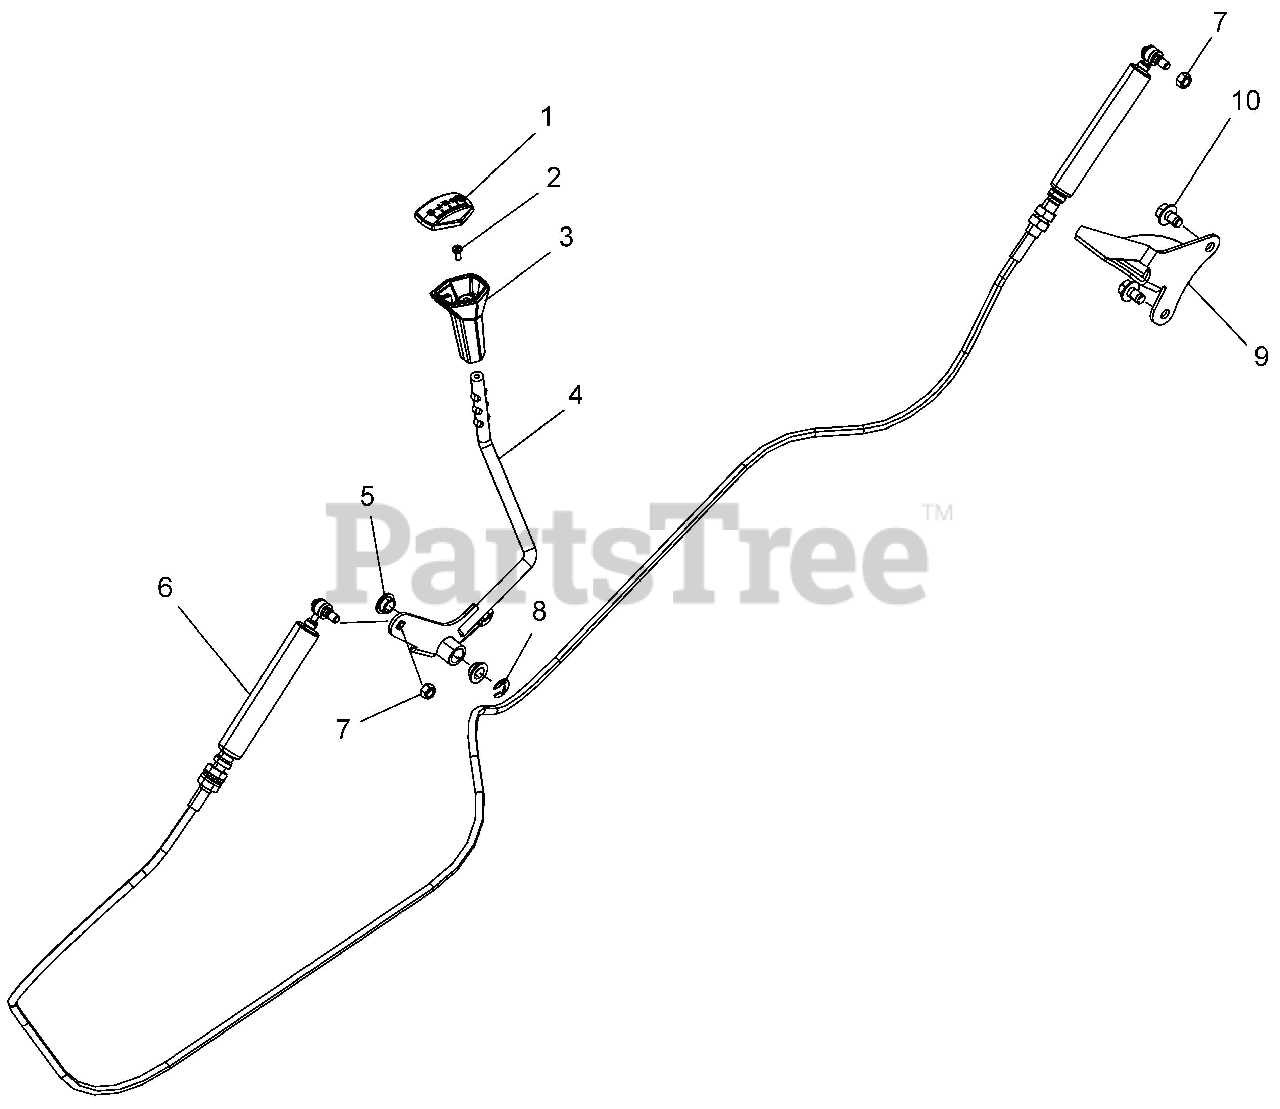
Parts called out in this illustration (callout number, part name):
1	COVER-SHIFT
3	KNOB-GEAR SELECTOR SHIFT
4	WELD-SHIFT LEVER,BLK
5	BUSHING-PEDAL PIVOT
6	CABLE, SHIFT
7	NUT,NYLOK M8X1.25(10) *
9	BRKT-SHIFT CABLE
10	BOLT-M10X1.25X16,HXHD,FLG
